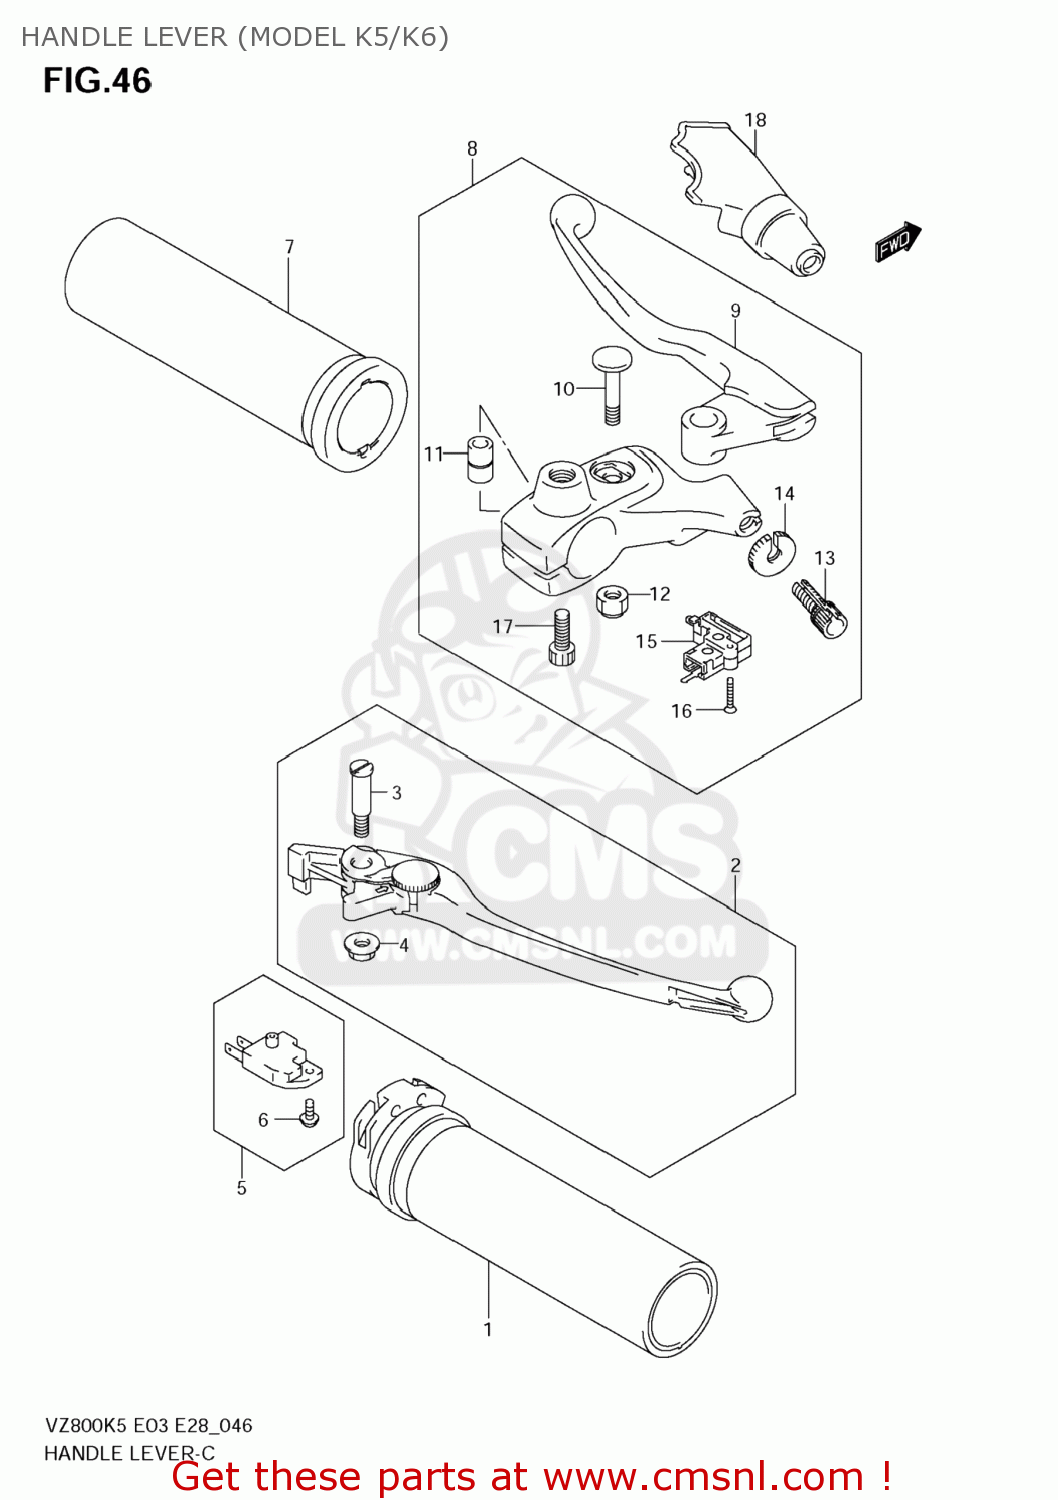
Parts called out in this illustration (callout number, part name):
1	GRIP,THROTTLE
2	LEVER ASSY,BRAKE
3	BOLT,LEVER PIVOT
4	NUT
5	SWITCH ASSY,ST
6	SCREW
7	GRIP,L
8	LEVER ASSY,CLUTCH
9	LEVER,CLUTCH
10	BOLT,CLUTCH LEVER
11	SPACER,CLUTCH LEVER PIVOT
12	NUT 6MM
13	ADJUSTER,WIRE
14	NUT,LOCK
15	SWITCH,CLUTCH
16	SCREW
17	BOLT
18	COVER,CLUTCH LEVER
